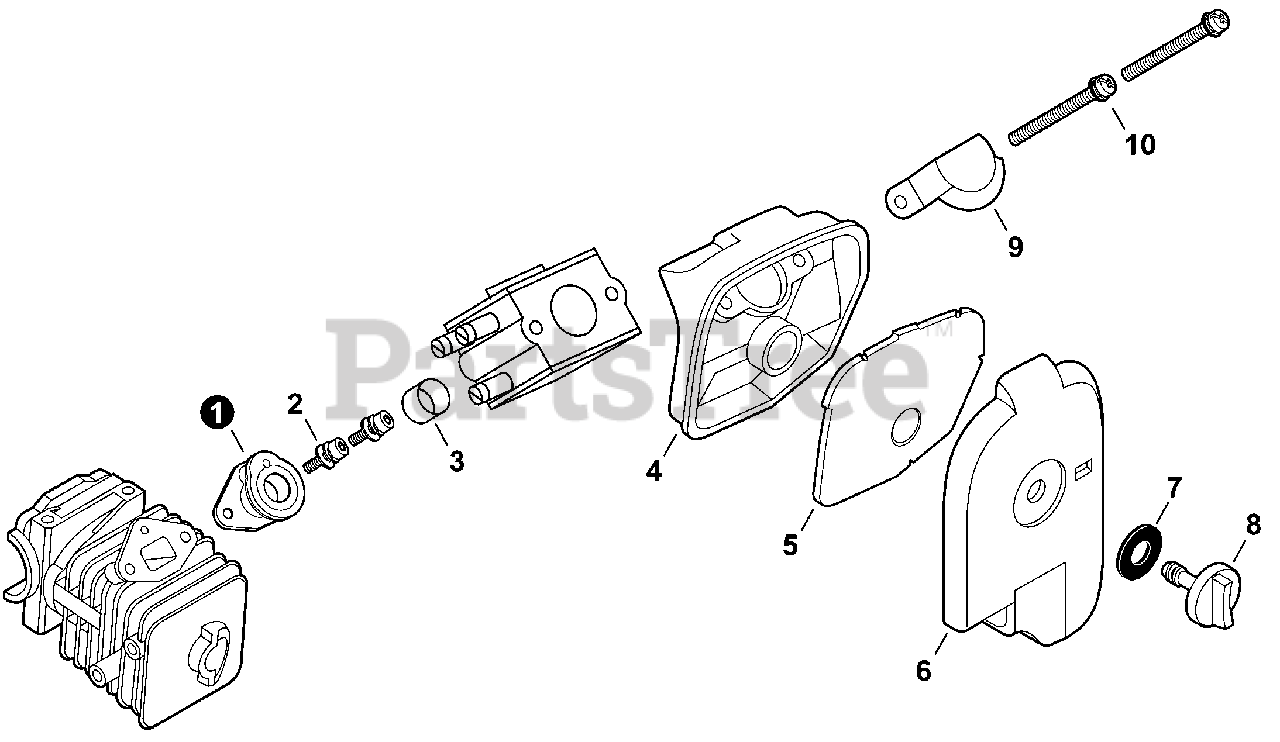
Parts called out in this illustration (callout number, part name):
1	BELLOWS, INTAKE
2	BOLT 4×12
3	COLLAR 14
4	CASE, AIR FILTER
5	FILTER, AIR
6	COVER, AIR FILTER
8	THUMBSCREW
9	PLATE, PREVENT
10	SCREW 5×50
